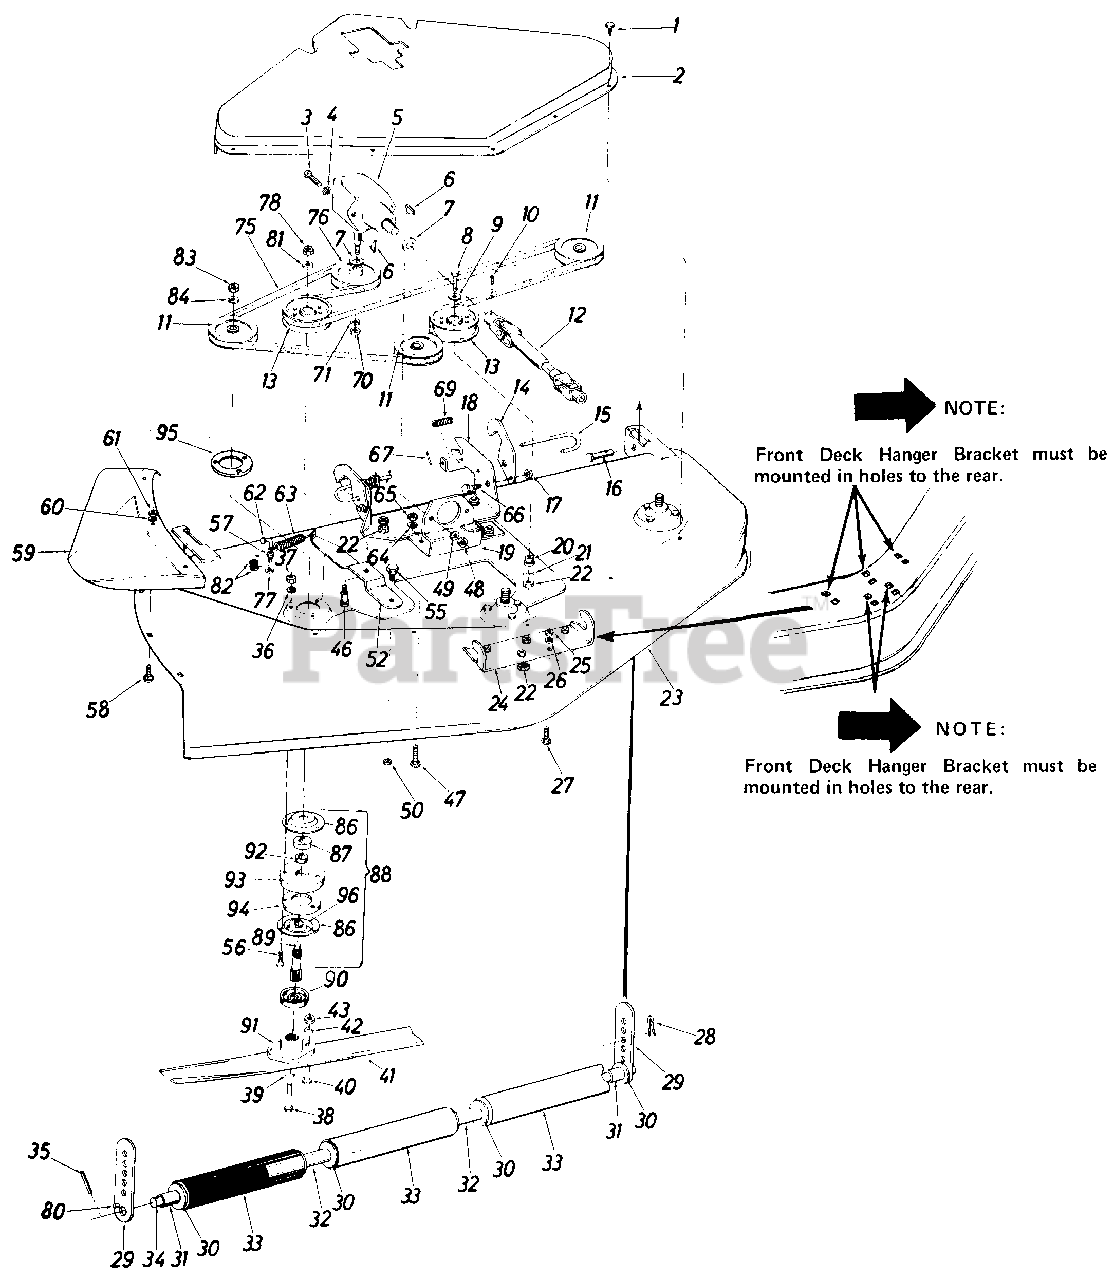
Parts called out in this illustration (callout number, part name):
1	Hex B Tap Scr. 1/4-20 x .38" Lg.
4	Ext. L-Wash. 3/8" Scr.*
5	Right Angle Drive
6	#9 Hi-Pro Key 3/16 x 3/4" Dia.
7	Fl-Wash. 29/32 I.D.
8	Hex Scr 3/8-16 x 2.25" Lg.*
9	Fl-Wash. 3/8" I.D.
10	Sq. Hd. Set Scr. 3/8-16 x . Lg. Cup
11	Deck Pulley
12	Universal Drive Shaft Ass'y.
13	Deck Idler Pulley
14	Hanger Lock
16	Clevis Pin .500 Dia.
17	Hex Cent. L-Nut 5/16-18 Thd.
21	L-Wash. 3/8" Scr.*
22	Hex Nut 3/8-16" Thd. *
26	L-Wash. 5/16" Scr.*
27	Carriage Bolt 5/16-18 x l.00" Lg. *
28	Internal Cotter Pin
30	Fl-Wash. .75 I.D. x 1.5 O.D.
31	Spacer . 758 I.D. x 1. 25 O. D. x .530
34	Roller Shaft
35	Roll Pin 3/16 x 1.25
36	L-Wash. 5/16" Scr.*
37	Hex Cent. L-Nut 5/16-24 Thd.
38	Hex Scr. 3/8-24 x .75" Lg. Thd. Rolling
39	L-Wash. 3/8" Scr. H.D.
40	Hex Scr. 5/16-24 x 1.00" Lg.
41	Blade 17"
42	L-Wash. 5/16" Scr.*
43	Hex Cent. L-Nut 5/16-24 Thd.
46	Hex Scr. 5/8 18 x 1.31" Lg.
47	Carriage Bolt 5/16-18 x .75"
48	Hex Nut 3/8-16 Thd.
49	L-Wash. 3/8" Scr.*
50	Hex Cent. L-Nut 7/16-14
56	Hex Scr. 5/16-24 x 1.50" Lg. (Grade 5)
57	Hex Nut 1/4-20 Thd.*
58	Carriage Bolt 5/16-18 x .75" Lg.*
60	L-Wash. 5/16" Scr.*
61	Hex Nut 5/16-18 Thd.*
63	Extension Spring
64	L-Wash. 5/16" Scr.
65	Hex Nut 5/16-18 Thd.*
67	Roll Pin 1/8" Dia.
69	Compression-Spring
70	Hex Cent. L-Nut 5/8-18 Thd.
71	L-Wash. 5/8" Scr.*
75	"V"-Belt
76	Drive Pulley
77	Hex Cent. L-Nut 1/4-20 Thd.
78	Hex Cent. L-Jam Nut 5/8-18 Thd.
80	Spring Pin Spiral 1/4" Dia. 1.00" Lg.
81	Fl-Wash..62" I.D.
82	Ext. L-Wash. 1/4" Scr.*
83	Hex Jam Nut 5/8-l8Thd.
84	L-Wash. 5/8" I.D.*
86	Bearing Housing
87	Ball Bearing
88	Deck Spindle Ass'y.
89	Spindle
90	Bearing Shield
91	Blade Adapter
93	Spindle Spacer Plate
94	Reinforcement Plate
95	Spirldle Reinforcement Plate
96	Open Bearing Housing
